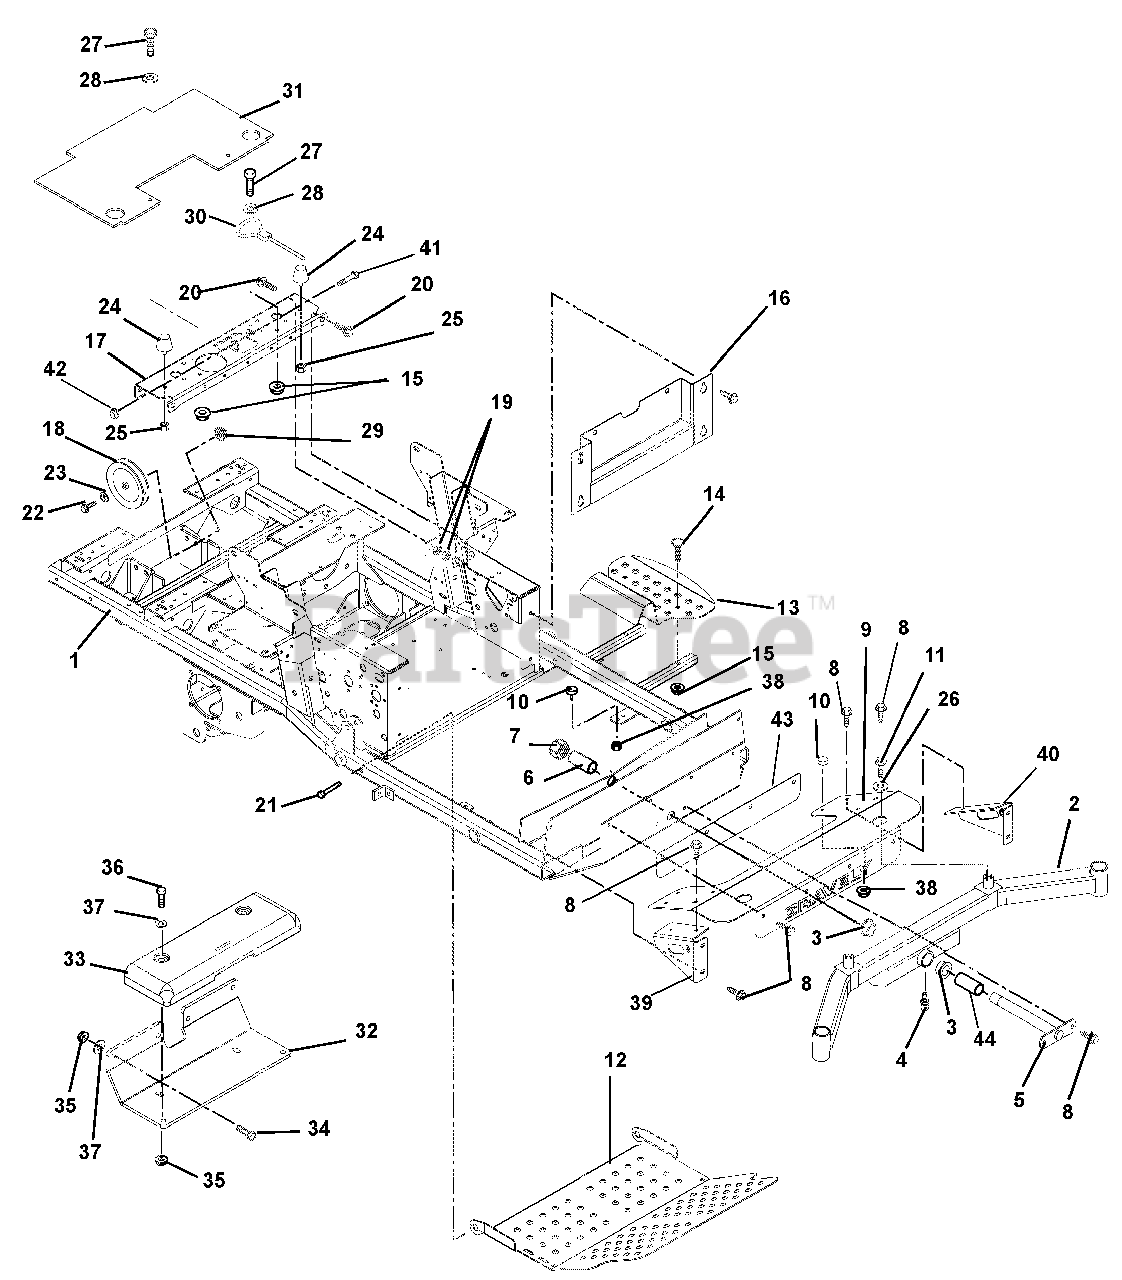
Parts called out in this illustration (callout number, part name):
1	WLDMT, FRAME
2	WMT, FRONT AXLE
3	BUSH, FLG 1.25X1.50X1.00X.200
4	FTG,LUBE 45 DEG
5	PIN - AXLE
6	SPACER 1.009 X 1.250 X 4.23
7	NUT-LK-NYL 1.0-14 YWZC
8	@SCR-TAP .38-16X.75 HWH TR YWZ
9	AXLE COVER
10	BUMPER, RUBBER
11	BLT-HEX .50-20X1.00 GR5 YWZC
12	PANEL-INSPECTION
13	STEP, INGRESS (BLACK)
14	@BLT-RDHDSQNK .31-18X1.75 G5YZ
15	@NUT-LK-TOP-FLG .31-18 YWZC
16	PLATE - KICK
17	BRACE, SEAT CROSS WITH LATCH
18	PLY-V 6.0 X .500 ID DBL BRG.
19	NUT-RTNR .375-16X.37
20	BLT-SERHFWH .375-16X1.0 YWZC
21	@BLT-HEX .50-13X3.25 GR5 YWZC
22	@BLT-HEX .50-13X2.25 GR5 YWZC
23	WSHR-FL-STL .505X.880X.072 YWZ
24	BUMPER, RUBBER CONE,STUD MOUNT
25	@NUT-SPNLK-FLG .312-18 YWZC
26	WSHR-FLT .640X1.75X.250 YWZC
27	@BLT-HEX .31-18X1.00 GR5 YWZC
28	WSHR-FL-STL .344X1.125X.135
29	@NUT-LK-TOP-FLG .50-13 YWZC
30	CABLE, SEAT PROP.
31	GUARD - GRASS
32	BRACKET - WEIGHT - 252
33	WEIGHT, CAST IRON
34	@BLT-HEX .50-13X1.25 GR5 YWZC
35	@NUT-LK-TOP-FLG .50-13 YWZC
36	@BLT-HEX .50-13X4.50 GR5 YWZC
37	@WSHR-FL-STL.531X1.06X.095YWZC
38	@NUT-SPNLK-FLG .312-18 YWZC
39	WMT - RH AXLE COVER SUPPORT
40	WMT - LH AXLE COVER SUPPORT
41	@BLT-HEX .38-16X3.00 GR5 YWZC
42	@NUT-LK-TOP-FLG .38-16 YWZC
43	PLATE, BACKER
44	SPCR, 1.25ODX1.0IDX3.63
